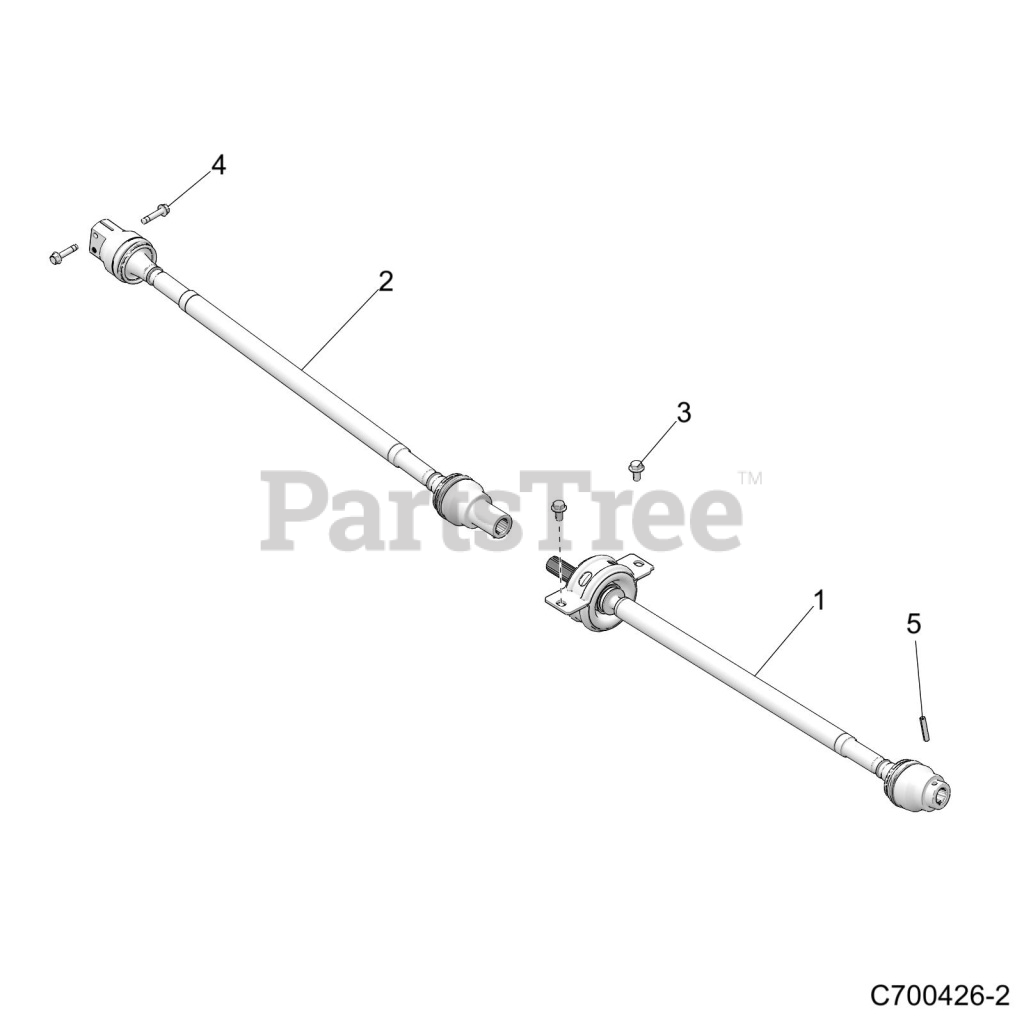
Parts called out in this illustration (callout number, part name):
1	ASM-PROPSHAFT,FRONT
2	ASM-PROPSHAFT,REAR
3	BOLT-M10X1.5X20,HXFLG,W/PATCH
4	SCR-HXFL-M8X1.25X40 8.8 ZODP30
5	PIN,SPRING(10)
